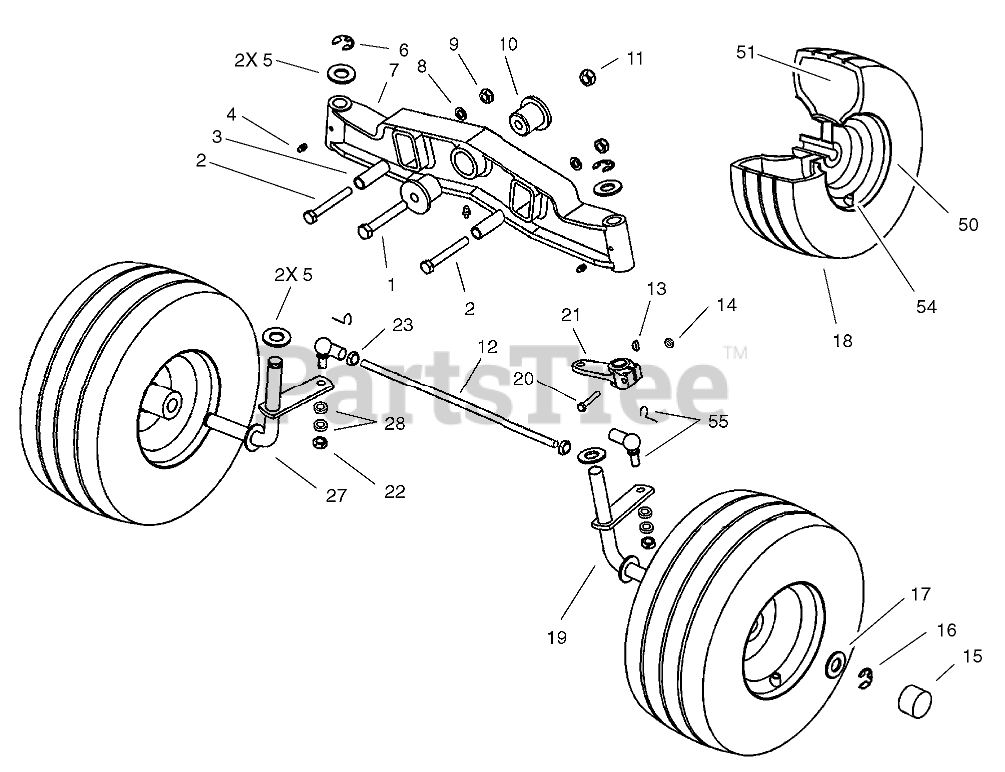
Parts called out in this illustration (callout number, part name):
1	SCREW-HH
2	SCREW-HH
3	SPACER
4	FITTING-GREASE
5	WASHER-FLAT
6	CLIP-SPRING
7	AXLE-FRONT
8	WASHER-FLAT
9	NUT-LOCK, NI
10	BUSHING-AXLE, FRONT
11	NUT-LOCKING, SELF
12	ROD-TIE, FRONT AXLE
13	KEY-WOODRUFF
14	NUT-LOCK
15	CAP-HUB
16	CLIP-SPRING
17	WASHER
18	FRONT TIRE WHEEL ASM
19	SPINDLE-LH
20	SCREW-HH
21	LEVER-SPINDLE, STEERING
22	NUT-HEX
23	NUT-HEX
27	SPINDLE-RH
28	Washer
50	TIRE- TURF SAVER 2 PLY
54	VALVE-TYRE
55	JOINT-BALL, ANGLE
